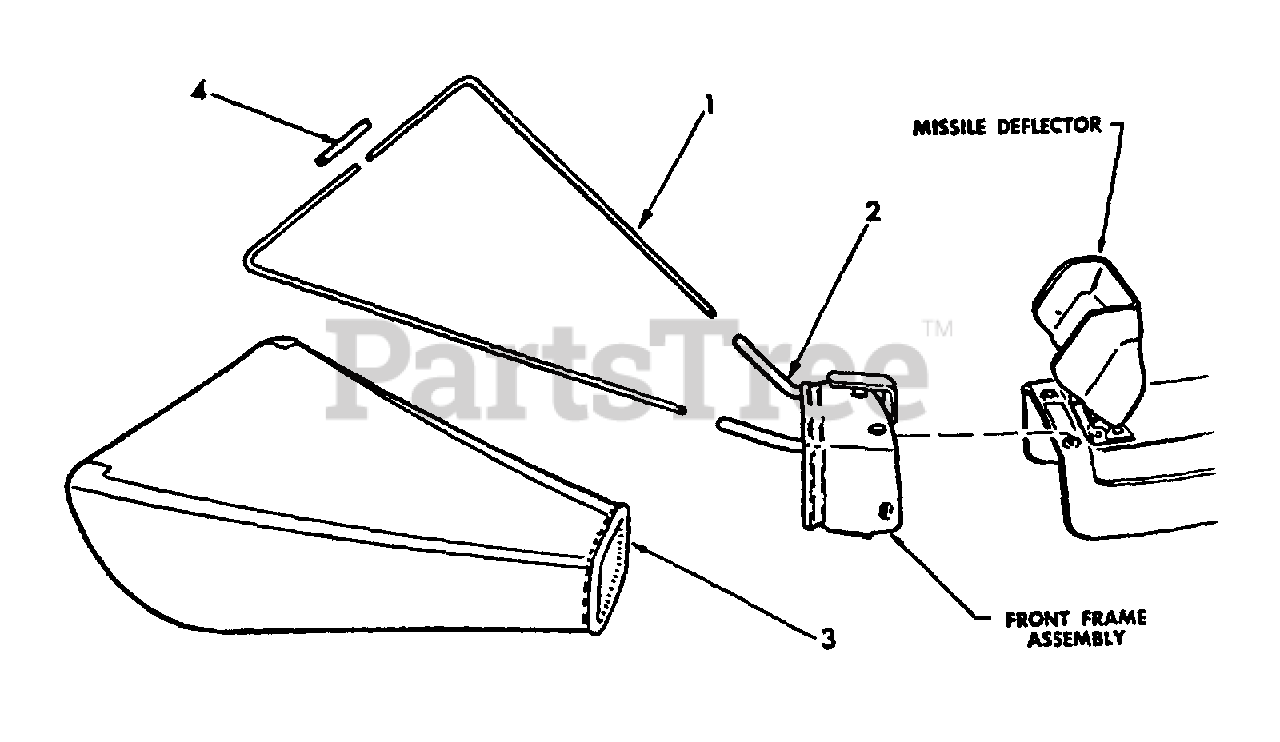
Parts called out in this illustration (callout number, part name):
1	SUPPORT, GRASS CATCHER
2	FRAME PKG, GRASS CATCHER
3	BAG, GRASS CATCHER
4	TUBE, FRAME COUPLER
